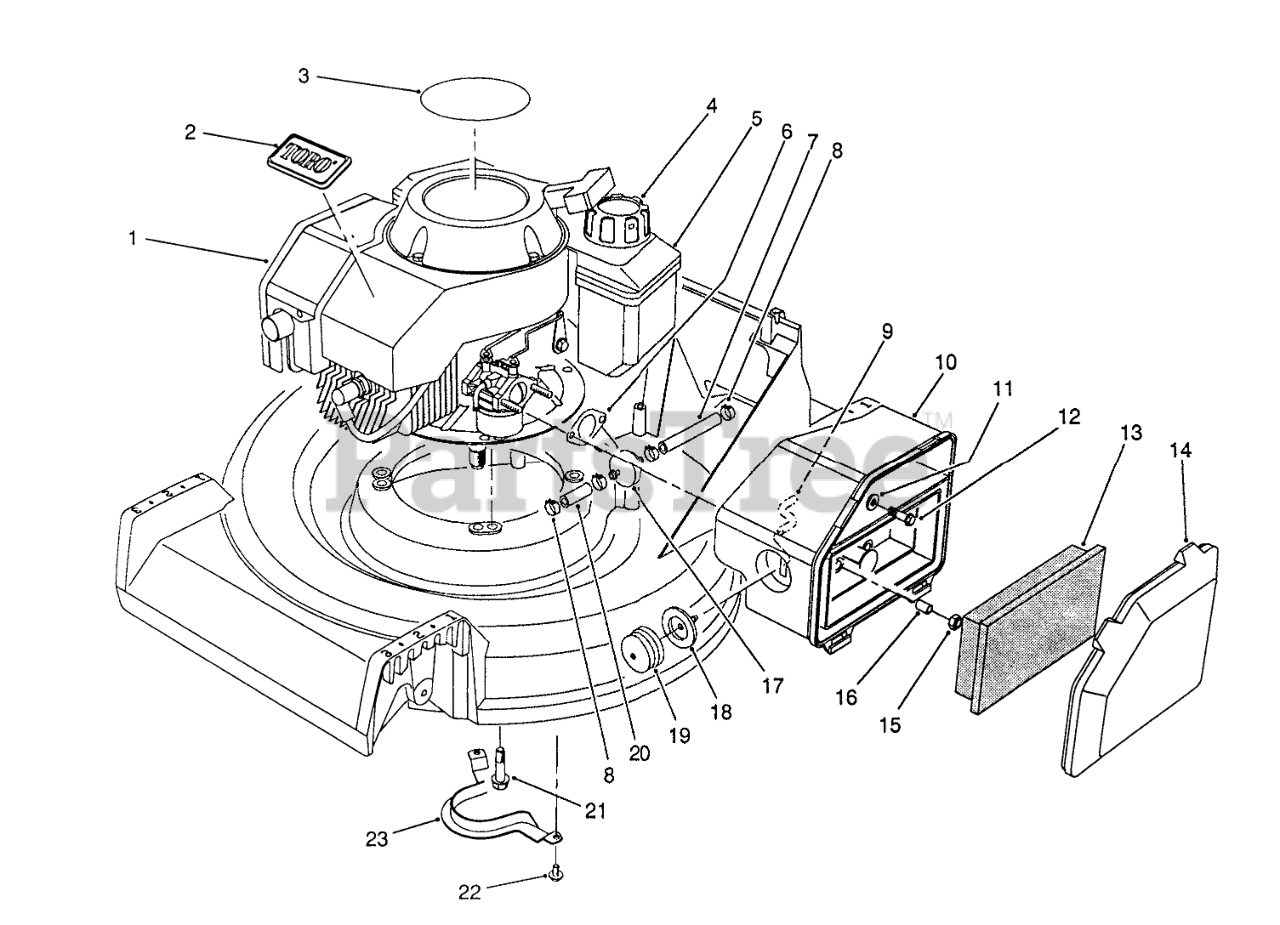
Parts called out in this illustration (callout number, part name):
1	Engine
2	TORO LOGO PLT
3	DECAL - 2 CYC RECOIL
4	GAS CAP ASM
5	FUEL TANK ASM
6	GASKET-AIR CLEANER
7	HOSE-FUEL
8	CLAMP-FUEL LINE
9	HOSE-PRIMER
10	BODY-AIR CLEANER
11	WASHER-FLAT
12	SCREW-HH
13	ELEMENT-AIR CLEANER
14	COVER-AIR CLEANER
16	SPACER
17	FILTER-FUEL
18	BODY-PRIMER
19	BULB-PRIMER
20	HOSE-FUEL
21	SCREW-HHF
22	SCREW-HWHTF
23	Guide-Belt
